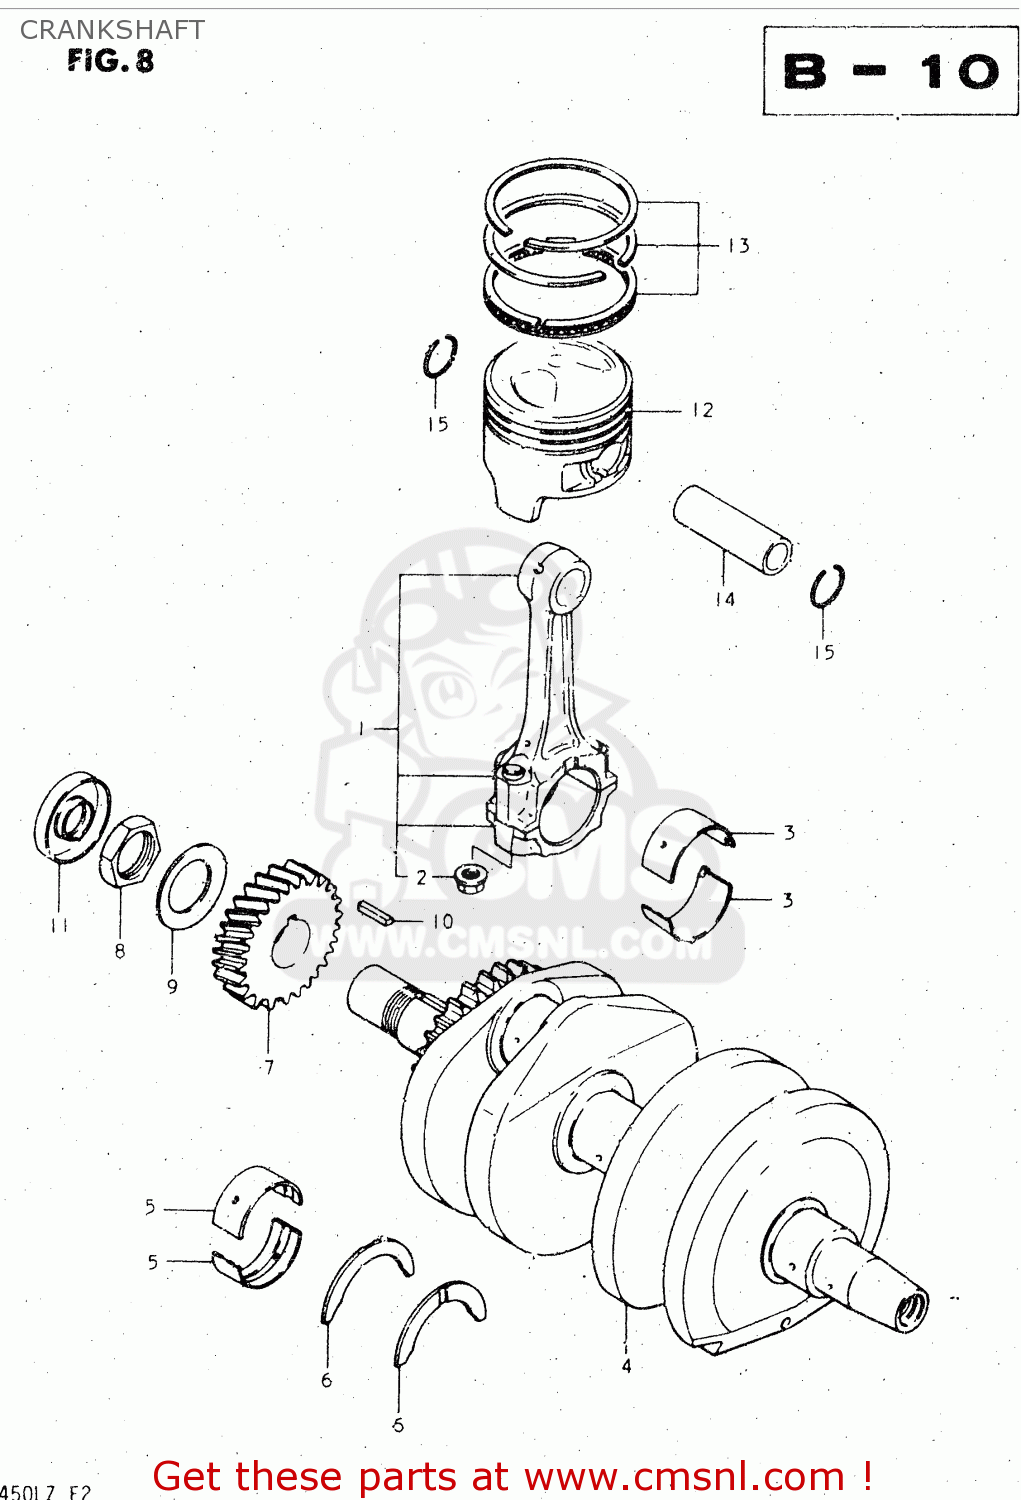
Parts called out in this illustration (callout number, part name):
1	ROD ASSEMBLY,CONNECTING
2	NUT
3	BEARING,CRANK PIN
4	CRANKSHAFT
5	METAL CRANKSHAFT
6	BEARING,CRANK THRUST
7	GEAR,PRIMARY DRIVE NO.28
8	NUT
9	WASHER
10	KEY
11	OIL SEAL
12	PISTON
13	RING SET,PISTON
14	PIN,PISTON (18MM)
15	CIRCLIP,PISTON PIN
